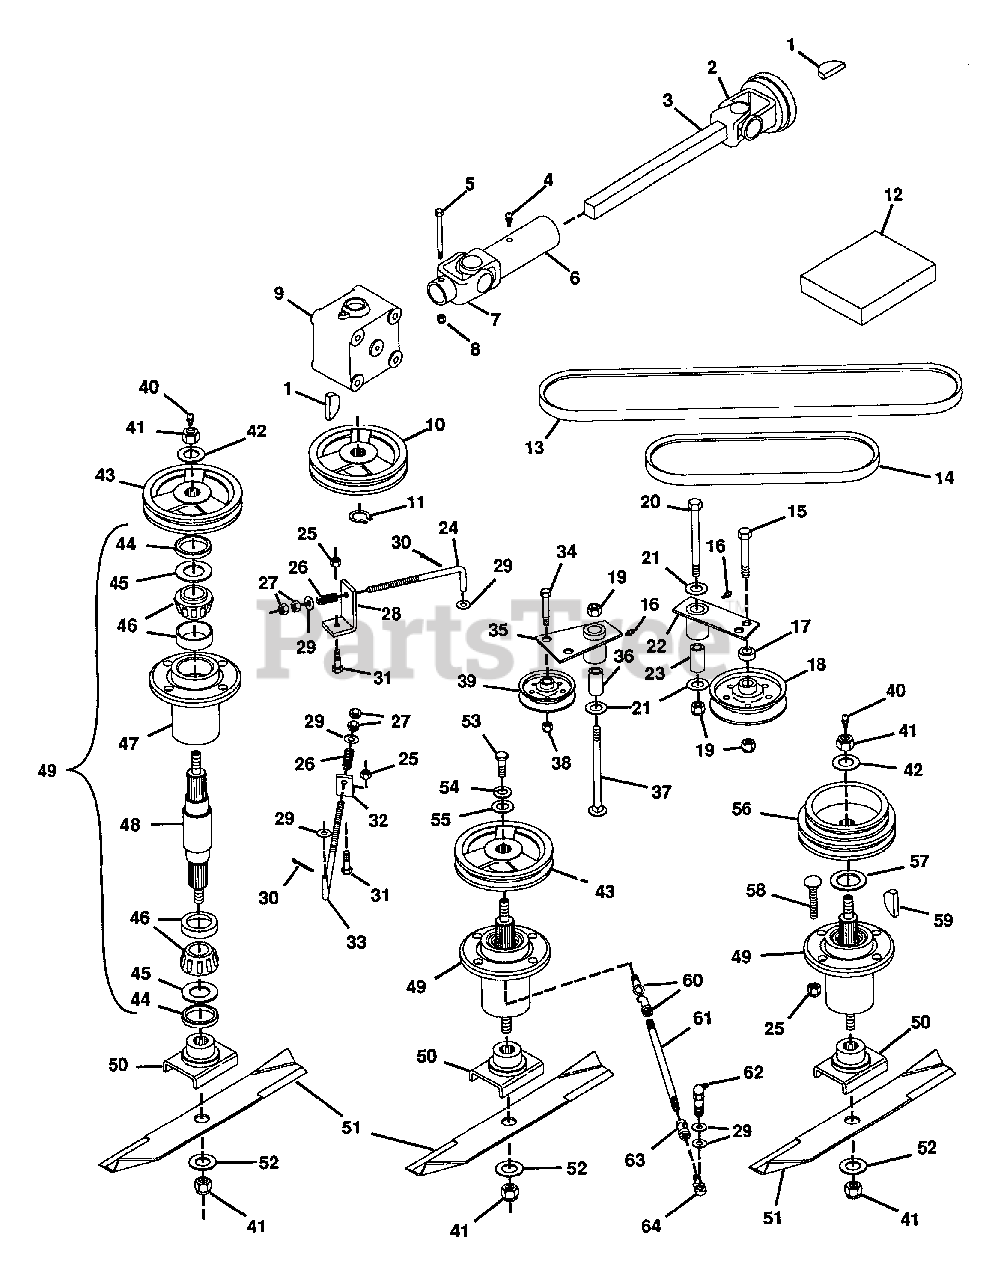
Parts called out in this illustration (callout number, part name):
1	Key, Woodruff .250x.875 Hard #A
3	Shaft, Prop. Sq. Bar
4	Fitting, Lube 1/4-28
5	Bolt, Hex 5/16-18x2.25
6	Assembly, U-Joint
8	Nut, Lock 5/16-18
9	Gearbox, Right Angle
10	Pulley, Gearbox
11	Ring, Retaining .875 Shaft
12	Kit, Repair Universal Shaft
13	Belt, "A"
14	Belt, "B"
15	Bolt, Hex 1/2-13x2.00
16	Fitting, Lube 1/4-28
17	Spacer, .516x.875x.300
18	Pulley, Flat Idler
19	Nut, Lock 1/2-13
20	Bolt, Hex 1/2-13x3.75
21	Washer, Flat .500x1 .250x.083
22	Weldment, Idler Pivot "B"
23	Spacer, .850x.546x2.50
24	Rod, Idler
25	Nut, Lock 3/8-16
26	Spring, Compression
27	Nut, Hex 3/8-24
28	Support, Spring "B"
29	Washer, Flat .406x.812x.065
30	Pin, Cotter .09x.75
31	Bolt, Hex 3/8-16x1.00
32	Support, Spring "A"
33	Rod, Idler
34	Bolt, Hex 3/8-16x1.75
35	Weldment, Idler Pivot "A"
36	Spacer, .850x.546x2.18
37	Bolt, 1/2-13x3.75 Rd Hd Sq Nk
38	Nut, Lock 3/8-16
39	Sheave, Idler
40	Fitting, Lube 1/8
41	Nut, Lock 5/8-11
42	Washer, Flat .687x1.312x.122
43	Pulley
44	Seal, Steel
45	Washer, Flat .975x1.970x.030
46	Assembly, Bearing Cup and Cone
47	Housing, Bearing Mower
47	Housing, Bearing
48	Shaft, Spindle (Right)
48	Shaft, Spindle (Center)
48	Shaft, Spindle (Left)
49	Assembly, Spindle (Right)
49	Assembly, Spindle (Center)
49	Assembly, Spindle (Left)
50	Weldment, Blade Cradle
52	Washer, Flat .656x1.312x.095
53	Bolt, Hex Spec. 1/2-13x1.34
54	Washer, Lock 1/2 Reg.
55	Washer, Flat 1.38x.56 Hard
56	Pulley, Drive
57	Race, Bearing Thrust
58	Bolt, 3/8-16x1.375 Rd Hd Sq Nk
59	Key, Woodruff .250x1.00 Hard #15
60	El, Street 1/8-27
61	Nipple, Pipe 6.30
62	Fitting, Lube 65 Degree
63	Coupling, Pipe 1/8-27
64	El, Adaptor 90 Degree
